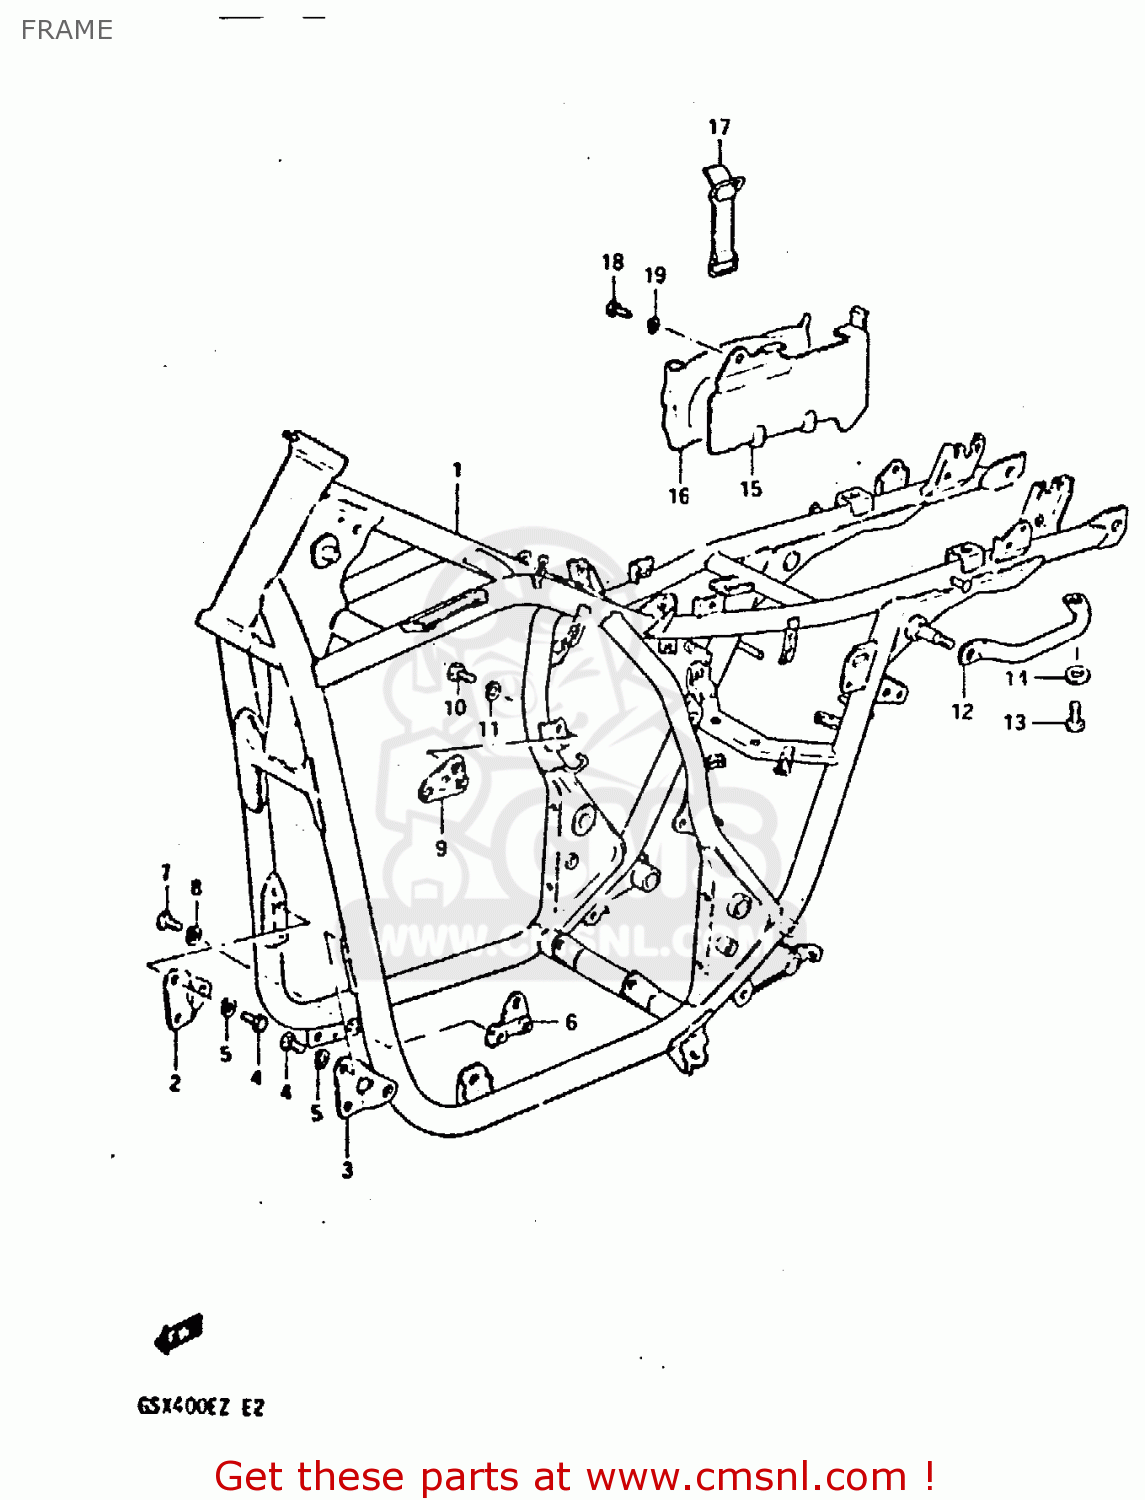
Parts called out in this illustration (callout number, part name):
1	FRAME
2	PLATE,ENG MTG NO.1,R
3	PLATE,ENGINE MOUNTING,LEFT
4	BOLT
5	LOCK WASHER
6	PLATE,MOUNTING NO.2,LEFT
7	BOLT
8	LOCK WASHER
9	PLATE,MOUNTING NO.4,LEFT
10	BOLT
11	LOCK WASHER
12	GRIP,FRAME HANDLE
13	BOLT
14	WASHER
15	HOLDER,TOOL
16	TOOL SET
17	BAND
18	BOLT
19	LOCK WASHER
